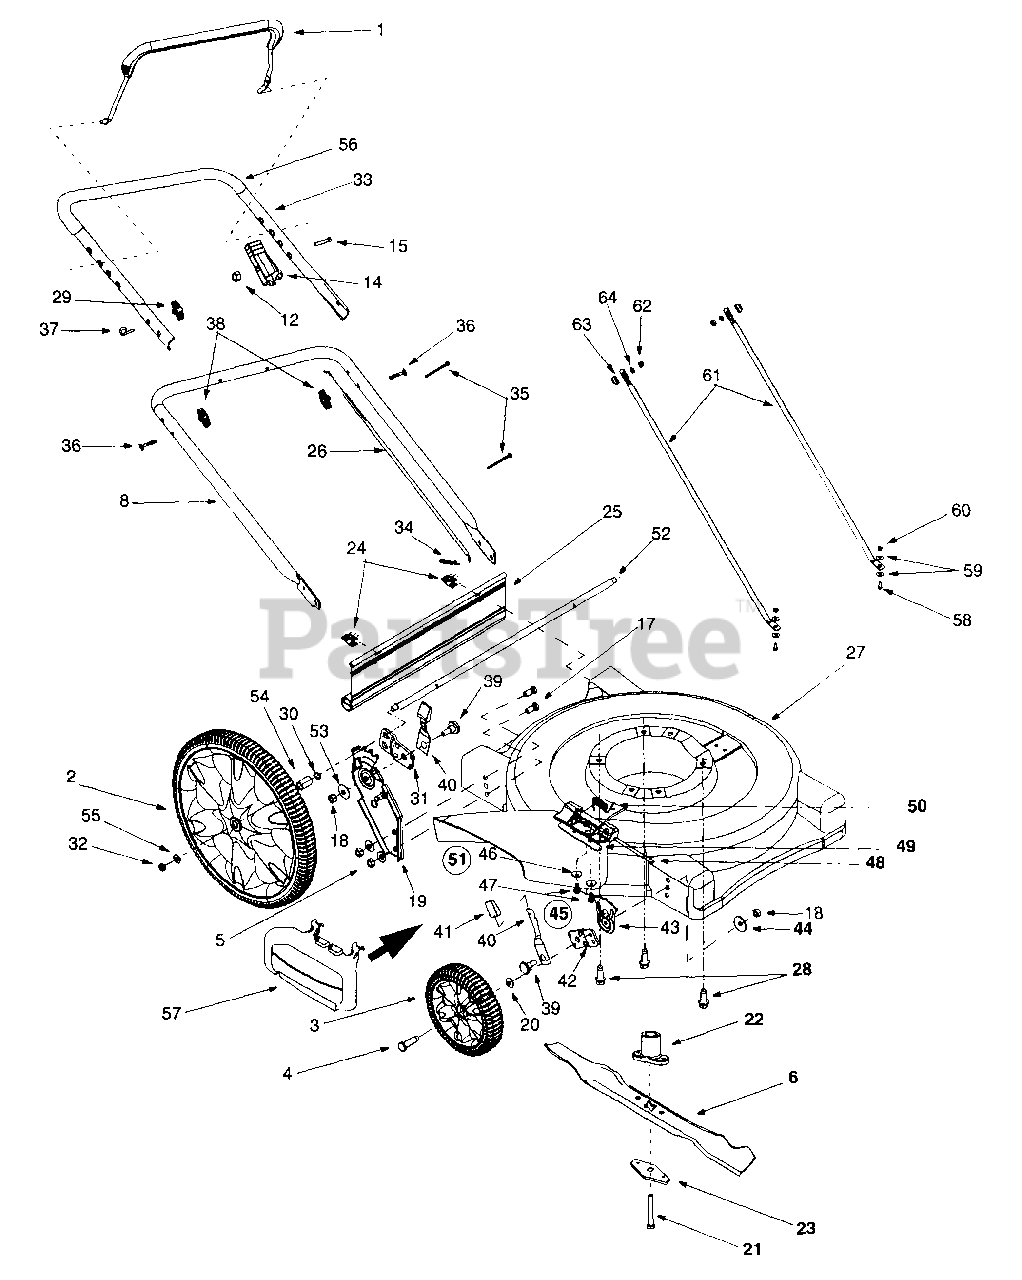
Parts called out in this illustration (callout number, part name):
2	Rear Wheel Bar Grey
3	Front Wheel Bar Grey
4	Front Axle Bolt
5	Hex Nut 3/8-24
6	Standard Blade 22"
14	Control Cable Housing
15	Hex Screw 1/4-20 x 1.3
17	Ribbed Neck Bolt 3/8-24 x .80
18	Hex Nut 3/8-16
21	Hex Bolt 3/8-24 x 1.5"
22	Blade Adapter
23	Blade Bell Support
24	Hinge Clip
25	Rear Flap Ass'y
26	Control Cable - B&S 43"
29	Handle Knob 1/4-20
30	Wave Washer
31	Pivot Bar - LH
32	Hex Jam Nut 3/8-16
35	Cable Tie
36	Curved Bolt 5/16-18 x 2"
37	Rope Guide
38	Hand Knob
39	Shoulder Bolt
40	Spring Lever Assembly
41	Knob
43	Height Adjuster Plate
44	Bell Washer
45	Front Height Adj Assembly - RH
46	Bell Washer
47	Hex Tap Screw 1/4-20 x .5"
48	Hinge Pin
49	Adapter Plate
50	Torsion Spring
51	Chute Deflector Ass'y
52	Rear Axle
53	Bell Washer
54	Spacer
55	Flat Washer
56	Foam Grip
57	Mulching Baffle
58	Hex Bolt 1/4-20 x .620
59	Bell Washer
60	Hex Nut 1/4-20
63	Saddle Washer
64	Lock Washer
